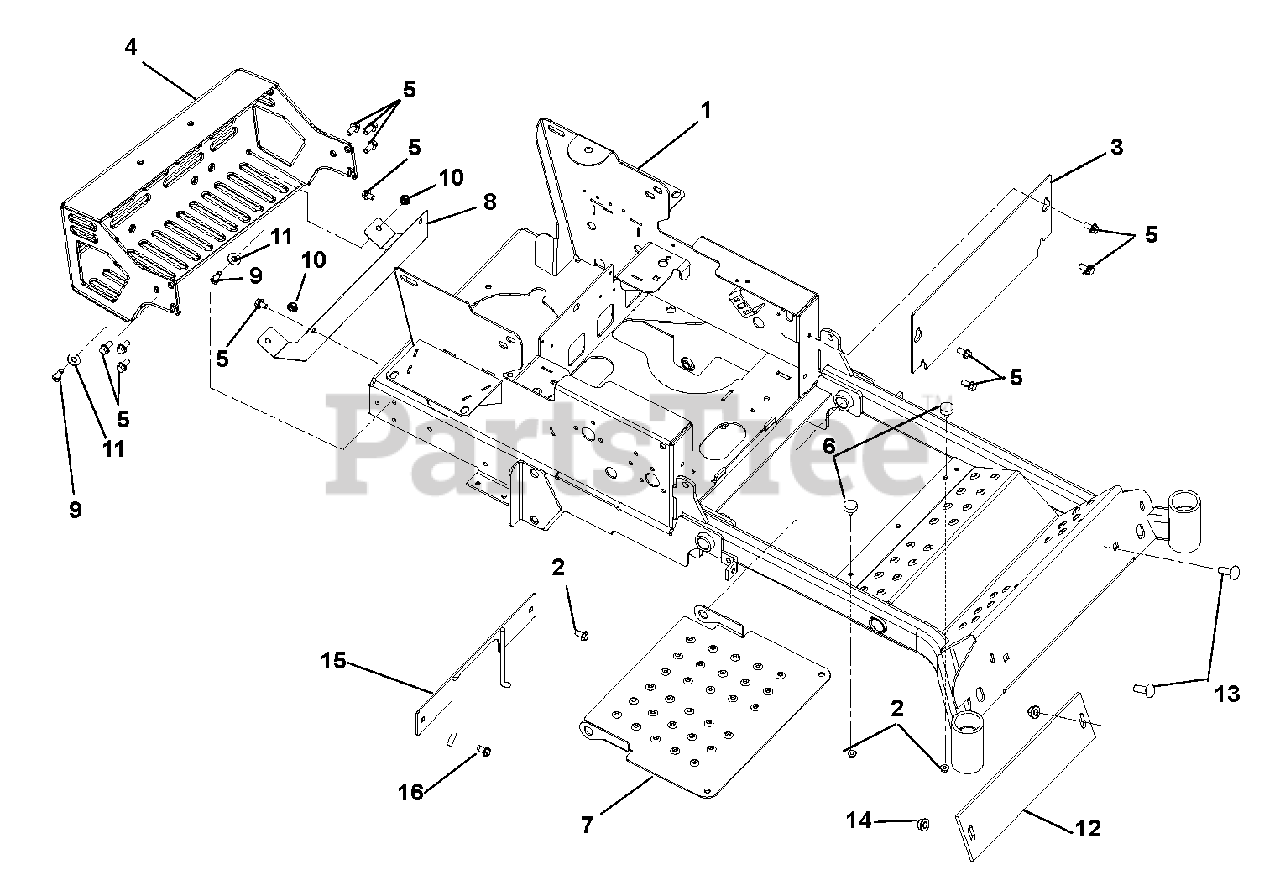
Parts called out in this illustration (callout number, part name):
1	Weldment, 44" – 48" HD Frame (991090, 082)
1	Weldment, 52" – 60" HD Frame (991083, 084)
2	Nut, Spin Lock Flange .312-18
3	Kick Plate
4	Bumper,Gravely HD
5	Screw, Tapping .38-16 x .75 Hex Washer Head
6	Bumper, Rubber
7	Panel, Inspection
8	Heat Shield
9	Bolt, Hex .38-16 x 1.00 Grade 5
10	Nut, Nyloc Flange .38-16
11	Washer, Flat Steel .438 x 1.00 x .083
12	Counterweight CZ Front
13	Bolt, Round Head Square Neck .50-13 x 2.25 Grade 5
14	Nut .50-13 Nyloc Flange
15	Weldment, PTO Belt Finger
16	Screw, Tapping .38-16 x .75 Hex Washer Head Thread
